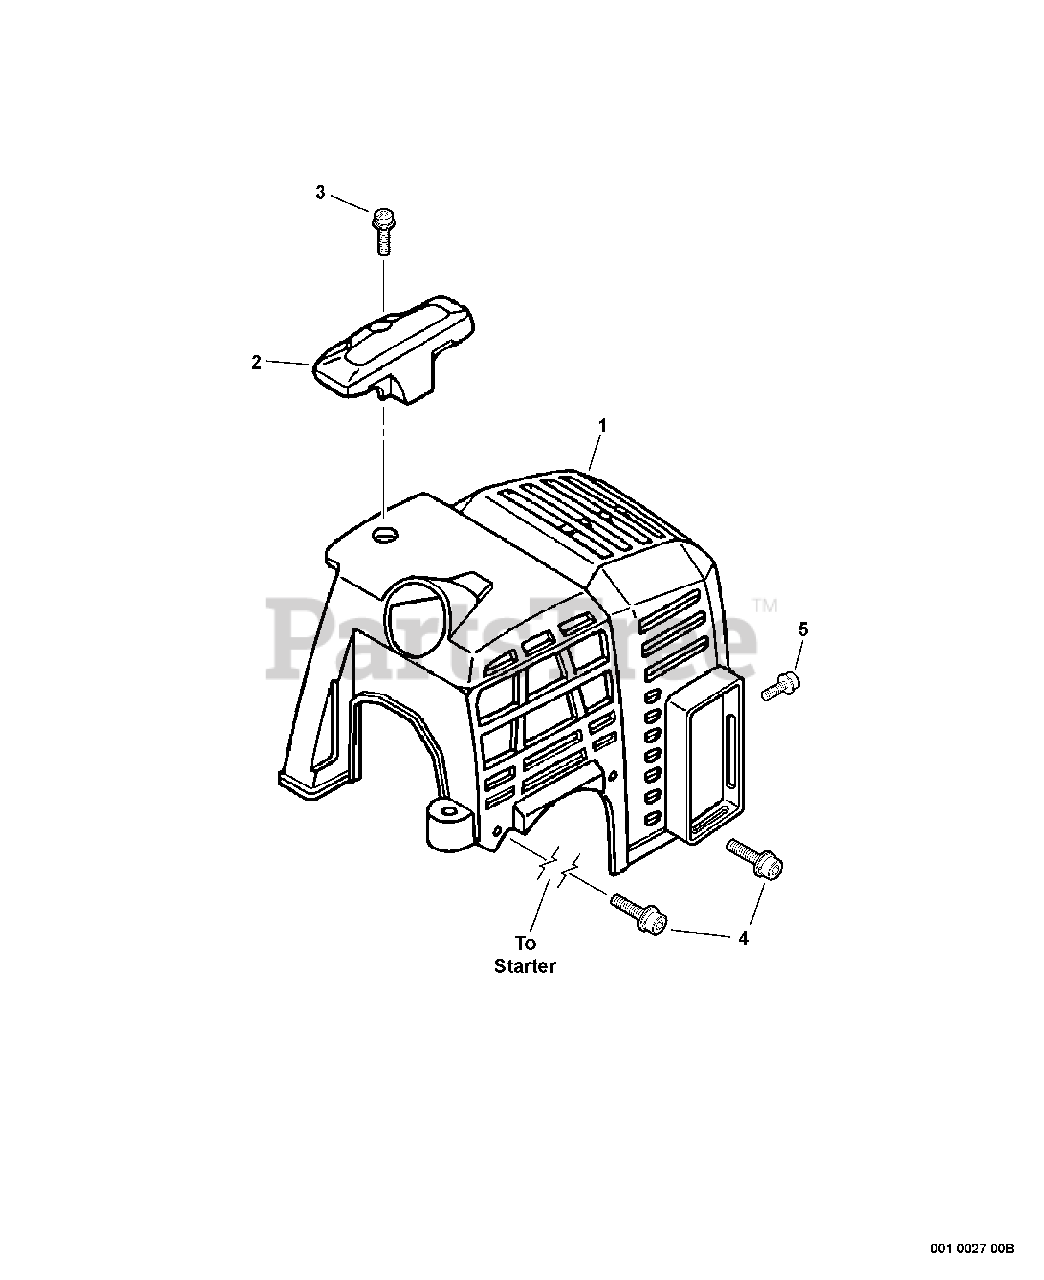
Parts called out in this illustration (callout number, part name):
1	COVER, ENGINE
2	GUARD - TOP
3	SCREW - 5X16
4	SCREW - 4X16
5	SCREW - 4X8
